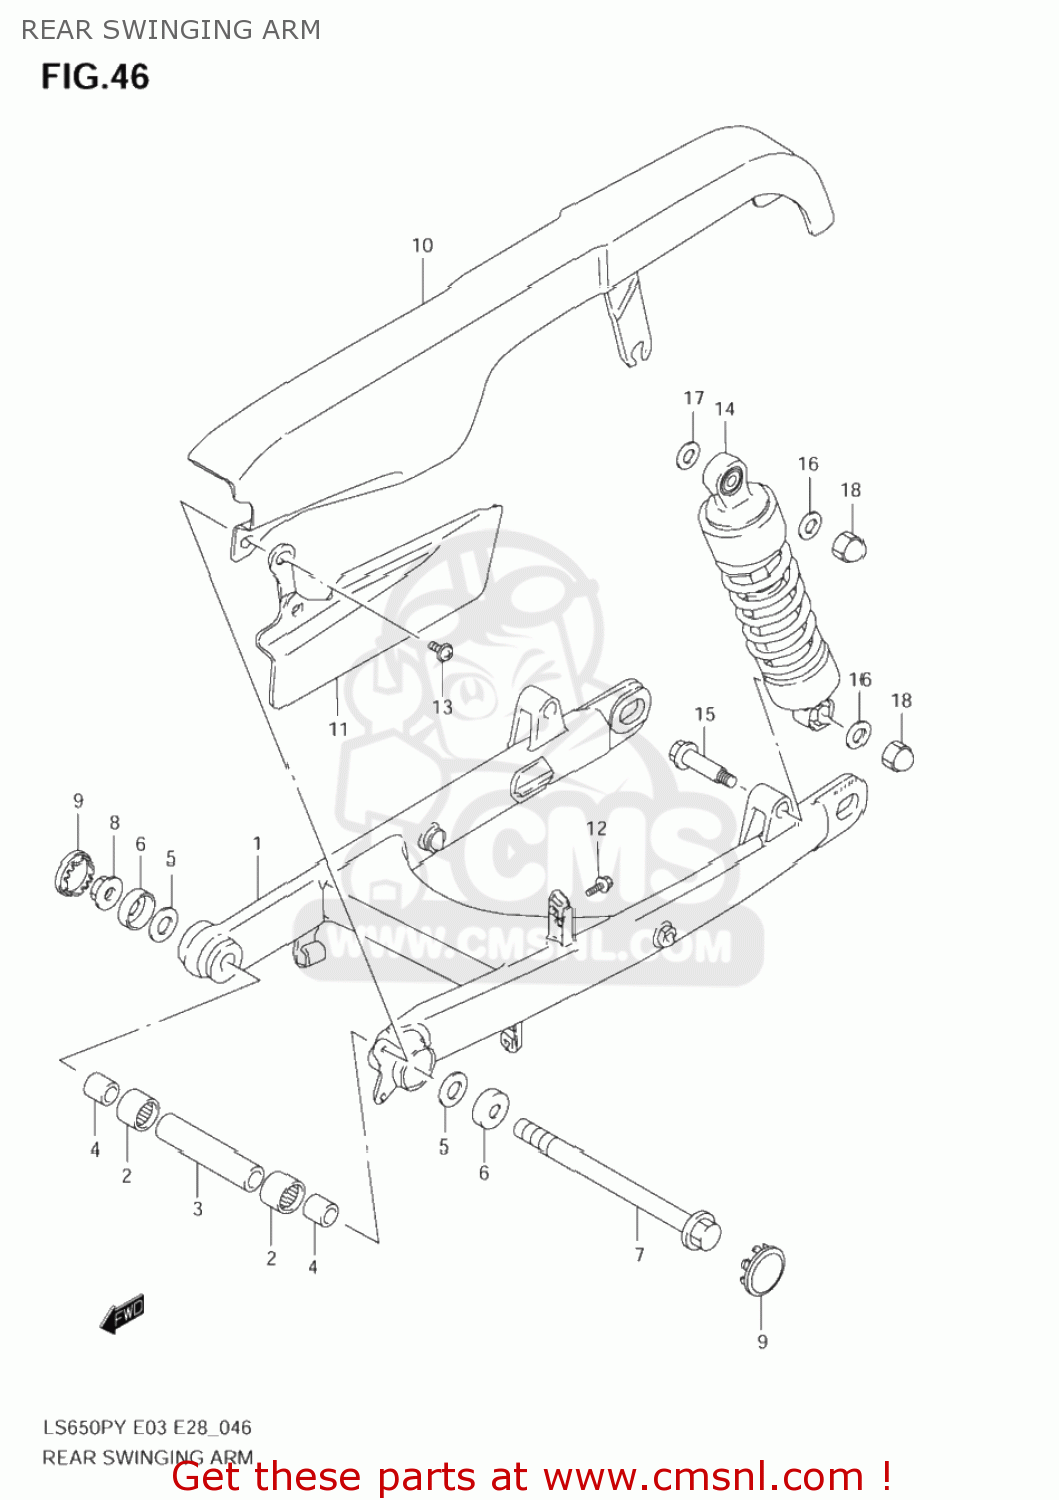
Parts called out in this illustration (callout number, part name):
1	SWINGINGARM,RR
2	BEARING(22X29X30)
3	SPACER,RR SWGARM PIVOT CTR
4	SPACER,RR SWGARM PIVOT
5	WASHER
6	CVR,RR SWGARM DUST SEAL(OD:40)
7	SHAFT,RR SWINGINGARM PIVOT
8	NUT
9	CAP,RR SWINGING ARM PIVOT,R
10	BELT CASE,UPR
11	BELT CASE,LWR
12	BOLT
13	SCREW
14	ABSORBER ASSY,RR SHOCK
15	BOLT,RR SHOCK ABSORBER LWR
16	WASHER(10.5X28X2.3)
17	WASHER(14.5X29X2.3)
18	NUT
